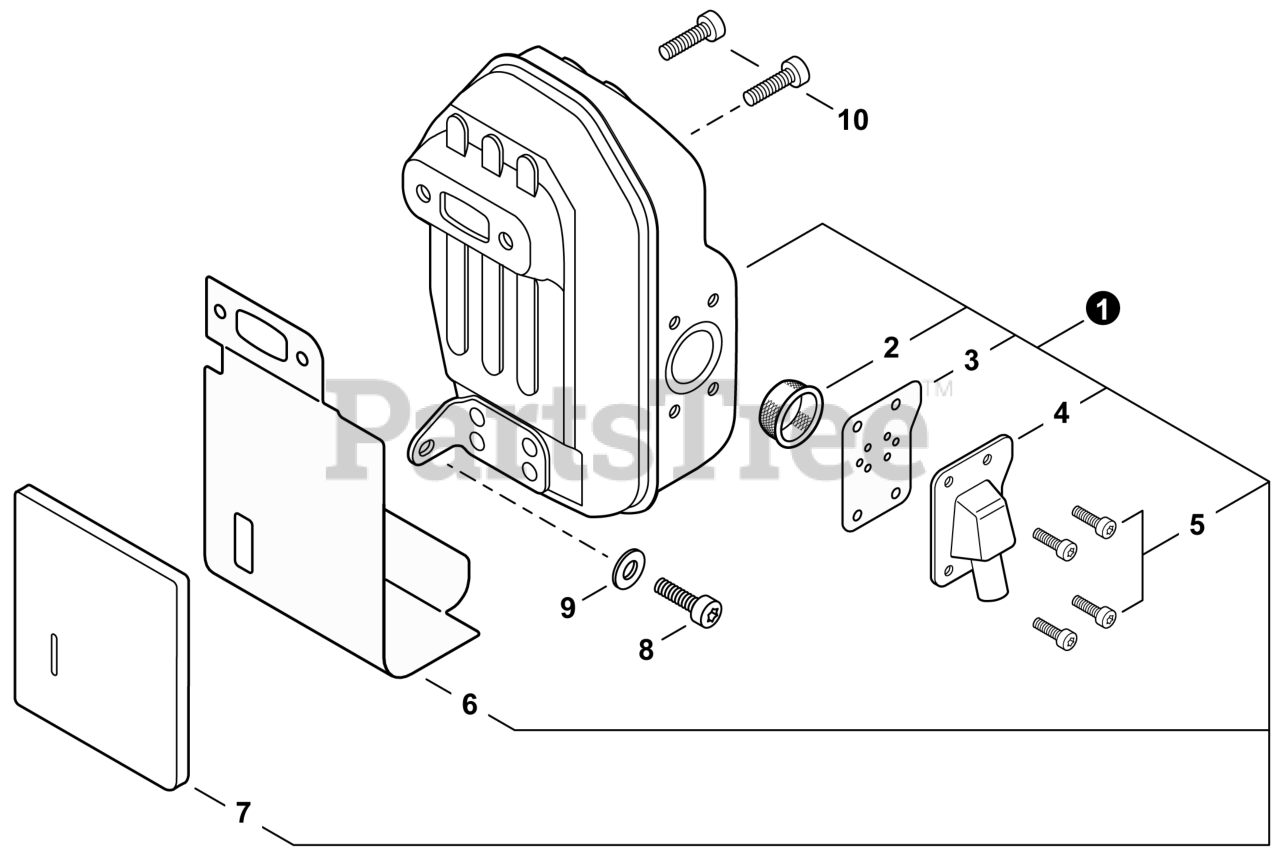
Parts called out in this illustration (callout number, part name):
1	MUFFLER ASSY
2	SCREEN, SPARK ARRESTER
3	GASKET, EXHAUST
4	GUIDE, EXHAUST
5	BOLT, TORX 4x8
6	HEAT SHIELD, EXHAUST
7	INSULATOR, MUFFLER
8	BOLT, TORX 5x16
9	WASHER 5.5x16x2T
10	BOLT, TORX 6x20
